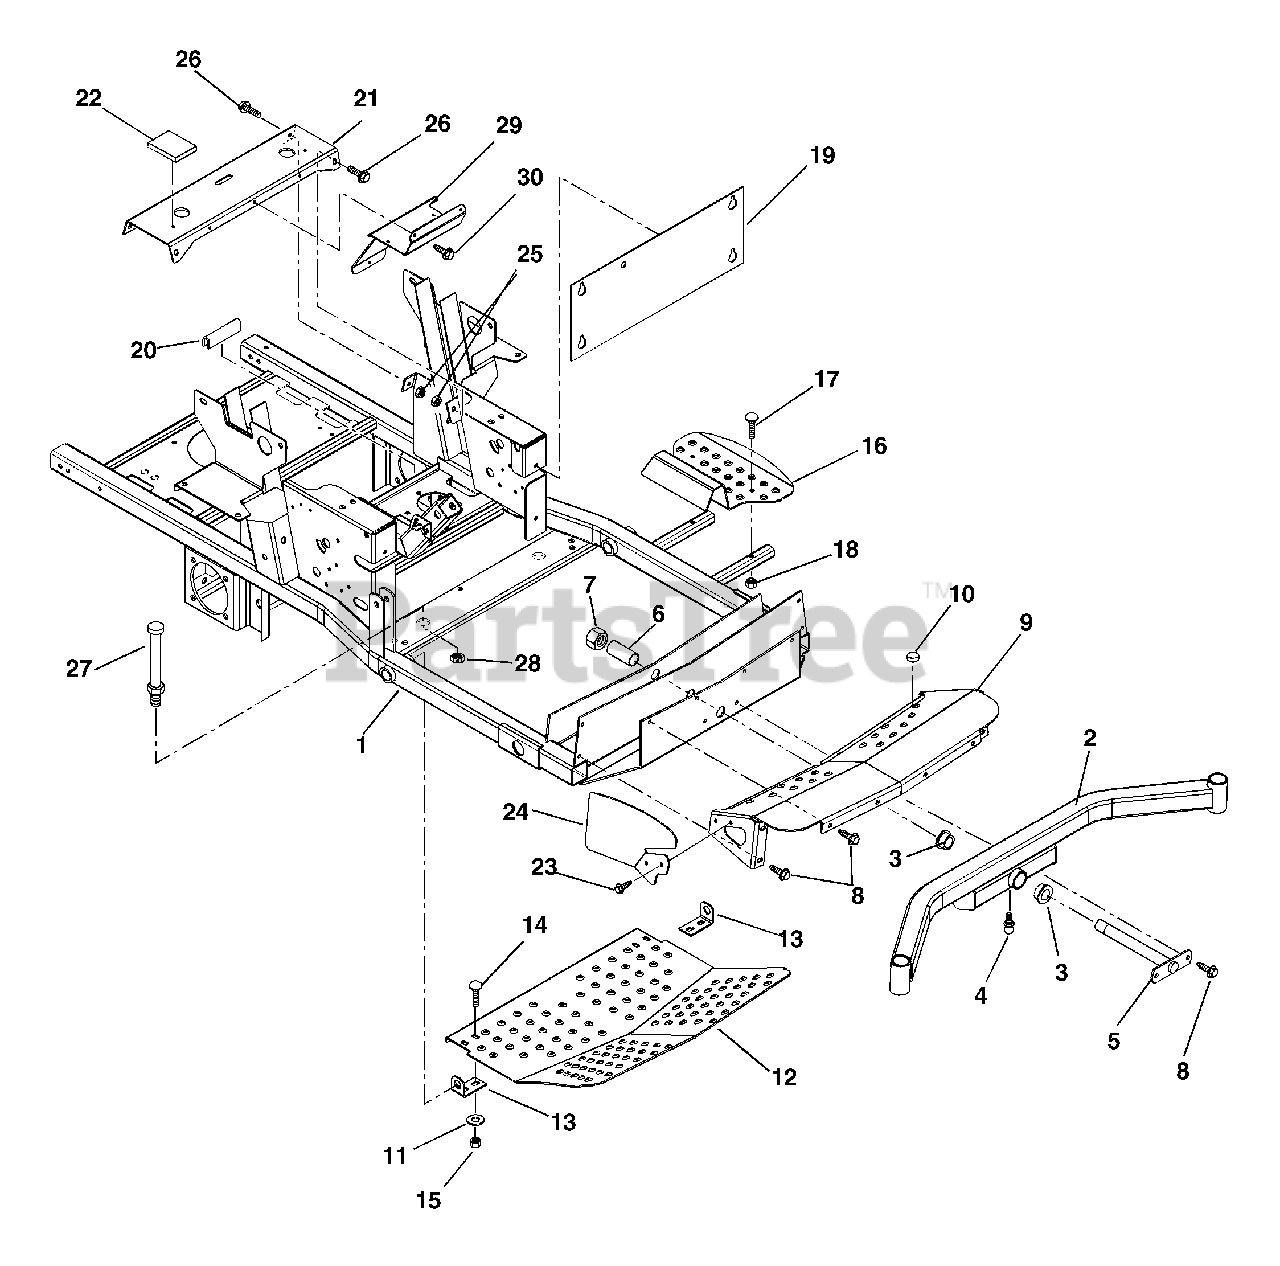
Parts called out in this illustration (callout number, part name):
1	Weldment, Frame
2	Axle-Front (020, 029, 033 034, 035)
2	Axle-Front (030, 032)
3	Bushing-Flange 1.020 x 1.385 x .75 x 1.75
4	Fitting-Lube .25-28 x .256
5	Pin-Axle
7	Nut-Locking-Nylon 1.0-14
8	Screw-Tapping .38-16 x .75
9	Cover-Axle
10	Button Bumper
11	Washer-Flat-Steel .38 x .875 x .083
12	Panel-Inspection
13	Mount-Inspection Panel
14	Bolt-Round Head Square Neck .38-16 x 1.00 Grade 5
15	Nut-Locking-Nylon .38-16
16	Step-Ingress
17	Bolt-Round Head Square Neck .31-18 x 1.50 Grade 5
18	Nut-Locking-Center .31-18
19	Plate-Kick
20	Strip -Cowl
21	Channel, Cross (Black)
22	Pad, Seat Frame
23	Screw-Tapping .25-20 x .50 Hex Washer Head
24	Cover, Cylinder Rod End
25	Nut-Retainer .375-16 x .37
26	Bolt-Serrated Flange Washer Head .38-16 x 1.00
28	Nut, Jam Center-Lock .75-16
29	Bracket, EFI Pump and Regulator (032, 033)
30	Screw-Tapping .25-20 x .50 Hex Washer Head
